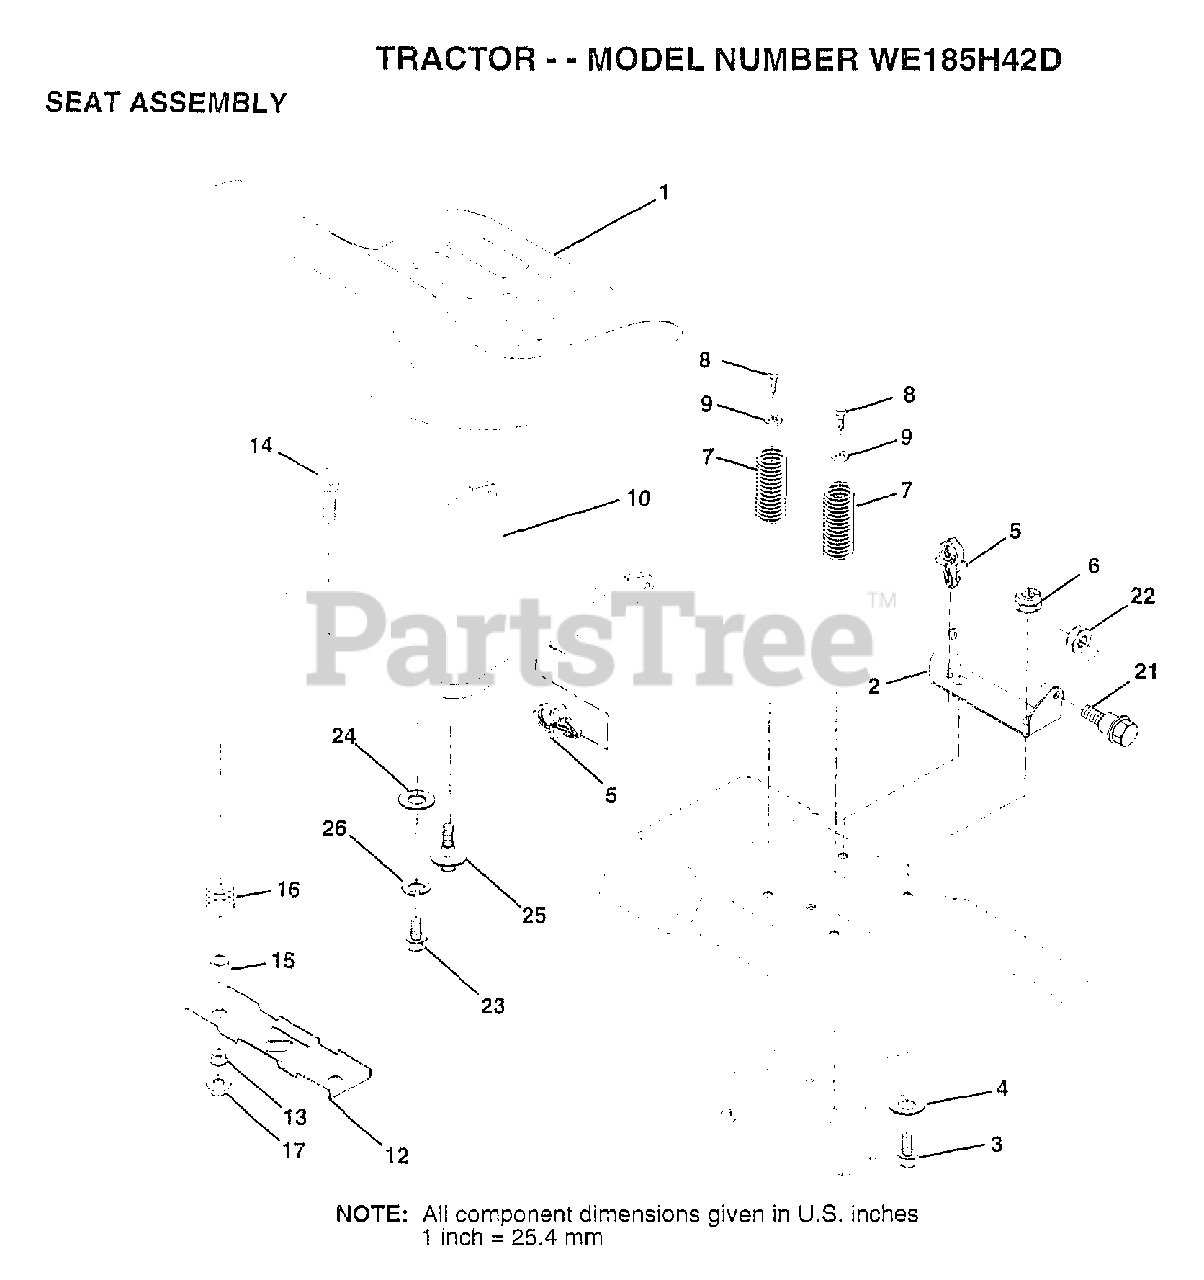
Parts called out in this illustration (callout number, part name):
2	BRACKET PVT SEAT
3	BOLT
4	WASHER PM
5	CLIP.PUSH-IN.HING
6	NUT
7	SPRING COMPRESSIO
8	SCREW GTV
9	WASHER
10	PAN-SEAT
12	BRKT SWITCH
13	BUSHING
14	BOLT-RD HD SQ NK
15	SPLIT SPACER
16	SPRING
21	"BOLT,SHOULDER"
22	NUT
23	BOLT
24	WASHER
25	"BOLT,SHOULDER"
26	LOCKWASHER
